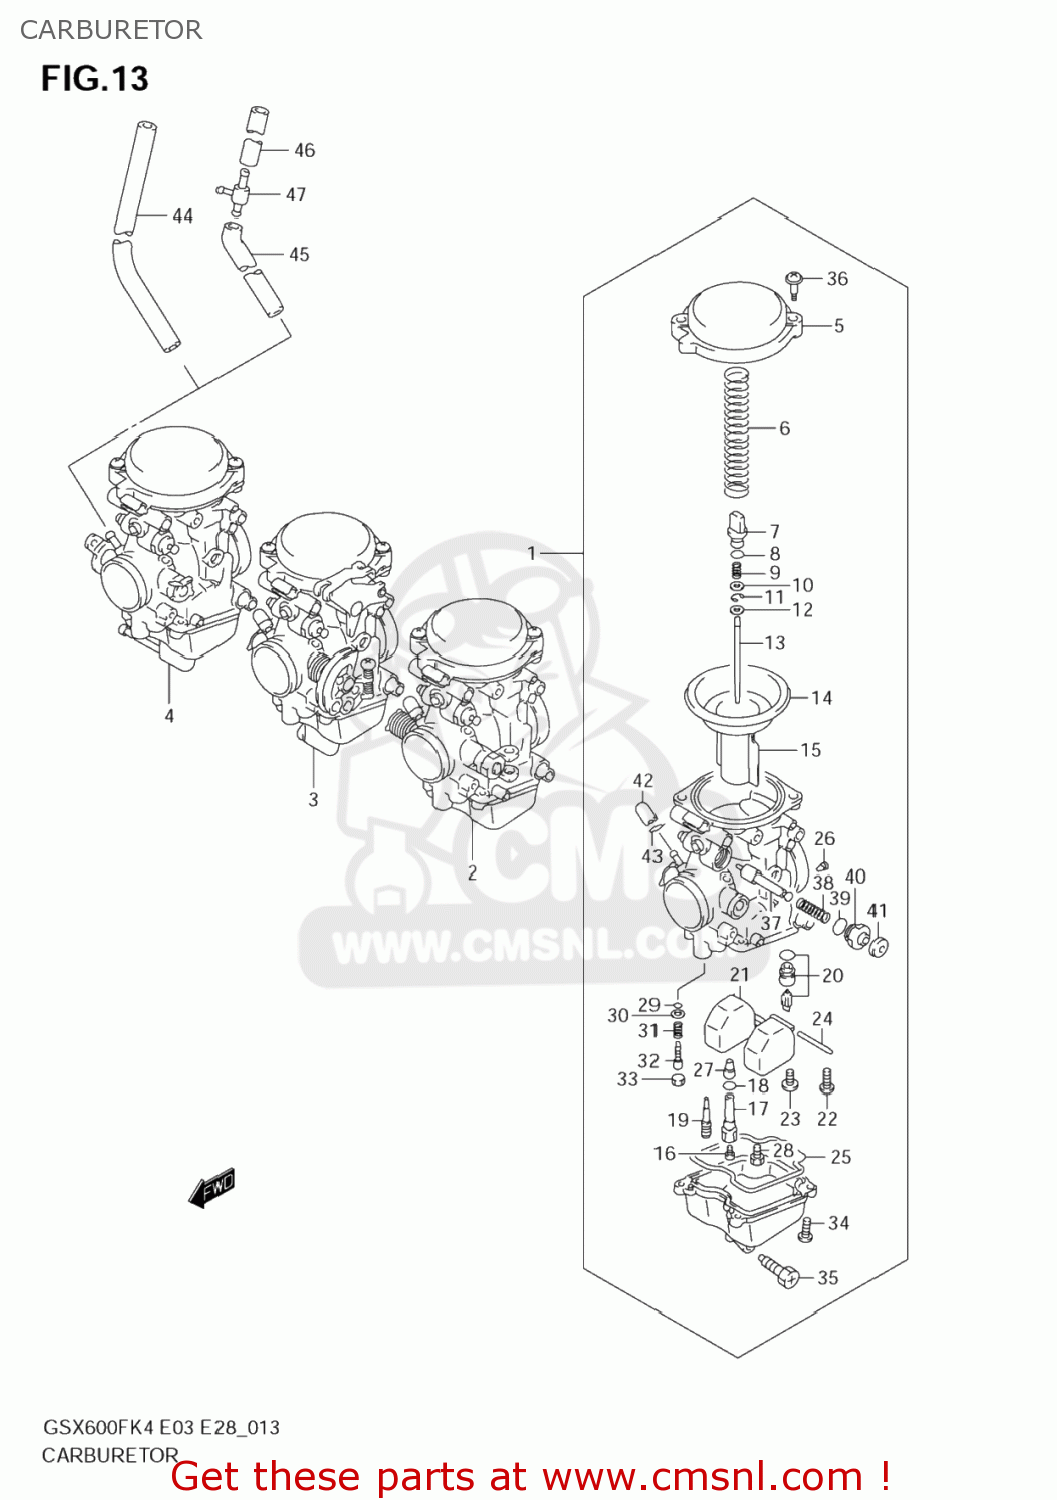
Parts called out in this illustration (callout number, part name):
1	CARBURETOR ASSY,L
2	CARBURETOR ASSY,ML
3	CARBURETOR ASSY,MR
4	CARBURETOR ASSY,R
5	COVER,DIAPHRAGM
6	SPRING
7	HOLDER
8	O RING(D:1.9,ID:4.8)
9	SPRING
10	WASHER
11	E RING,MULTIPLE JET NOZZLE
12	RING
13	NEEDLE,JET
14	DIAPHRAGM
15	VALVE,PISTON
16	JET,MAIN(115)
17	HOLDER,JET
18	O RING
19	JET,NEEDLE(P-0M)
20	VALVE ASSY,NEEDLE(ID:2.3)
21	FLOAT ASSY
22	SCREW
23	SCREW
24	PIN,FLOAT
25	GASKET (NAS)
26	JET,AIR(160)
27	JET,PILOT(12.5)
28	JET,STARTER(50)
29	O RING,PILOT AIR SCREW
30	WASHER
31	SPRING,THROTTLE SCREW
32	ADJUSTER
33	PLUG
34	SCREW
35	SCREW,DRAIN
36	SCREW
37	PLUNGER
38	SPRING
39	O RING
40	GUIDE SCREW,PLUNGER
41	CAP,STARTER VALVE
42	CAP
43	CLIP
44	HOSE(5X10X600)
45	HOSE(5X9X600)
46	HOSE(5X9X600)
47	NIPPLE
